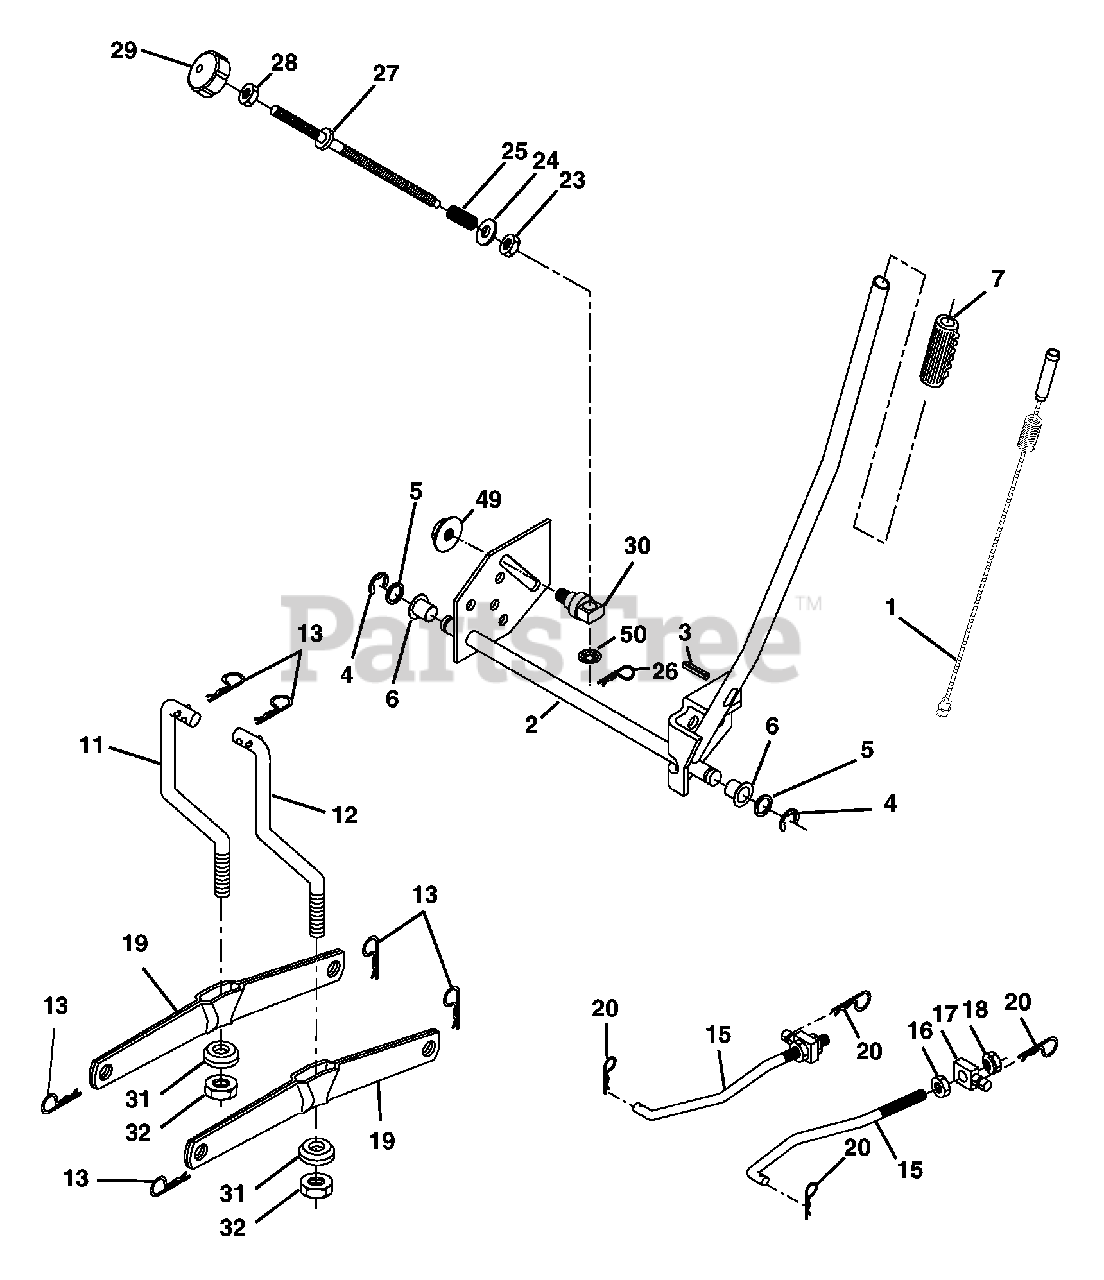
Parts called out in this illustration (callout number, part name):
1	Plunger Asm.
2	Shaft Asm Lift RH w/Inf
3	Pin Groove 2"
4	E Ring #5133-62
5	Washer 21/32 x 1 x 21 Ga.
6	Bearing Nylon Blk 629 Id
7	Grip Handle
11	Link Lift LH Fixed Length
12	Link Lift RH Fixed Length
13	Retainer Spring
15	Link Front
16	Nut Jam Hex 1/2-13 unc
17	Trunnion
18	Nut Lock W/Wsh 1/2-13 unc
19	Arm Suspension Rear
20	Retainer Spring
23	Nut Special
24	Washer 13/32 x 5/8 x 16 Ga.
25	Spring Infin. Height
26	Retainer Clip
27	Rod Adjust Lift
28	Nut Hex Jam 3/8-16 unc
29	Knob Infin. 3/8-16 unc
30	Trunnion Infi. Height
31	Bearing Pvt Lift
32	Nut Crownlock 3/8 - 24
49	Nut Hexflange Lock
50	Nut Push
